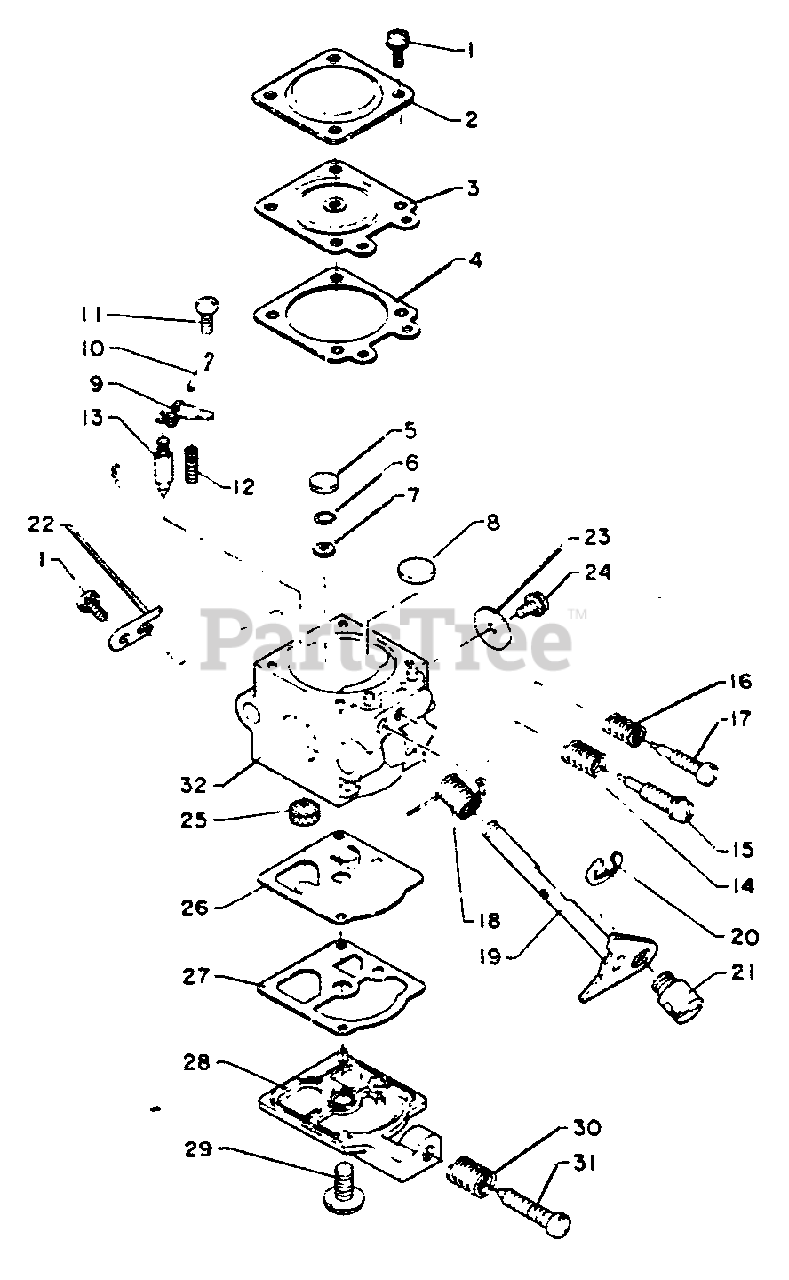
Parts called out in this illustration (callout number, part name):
2	COVER, METERING DIAPHRAGM
3	DIAPHRAGM, METERING
4	GASKET, METERING
5	PLUG, WELCH
6	RING, RETAINING
7	SCREEN, SPARK ARRESTER
8	PLUG, WELCH
9	LEVER, METERING
10	PIN, METERING LEVER
11	SCREW, METERING LEVER PIN
13	VALVE, INLET NEEDLE
14	SPRING, NEEDLE
15	NEEDLE, HIGH SPEED
16	SPRING, NEEDLE
17	NEEDLE, LOW SPEED
18	SPRING, THROTTLE RETURN
19	SHAFT, THROTTLE
20	RING, RETAINING
22	CLIP, THROTTLE SHAFT
23	VALVE, THROTTLE
25	SCREEN, FUEL INLET
26	DIAPHRAGM, PUMP
27	GASKET, FUEL PUMP
28	COVER, PUMP
30	SPRING, IDLE ADJUST
31	SCREW, IDLE ADJUST
32	BODY, CARBURETOR
